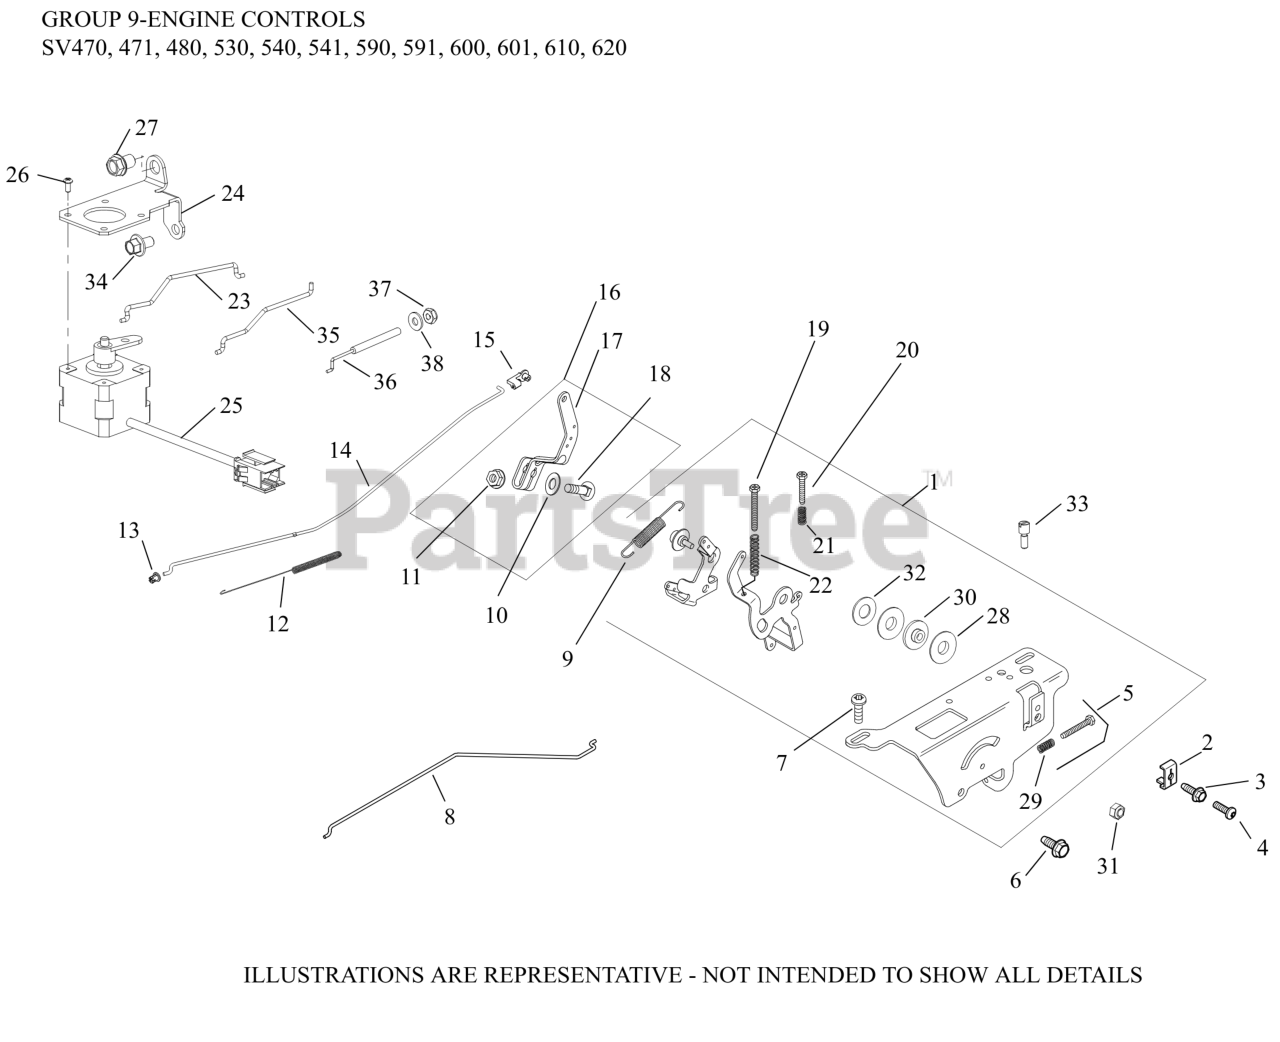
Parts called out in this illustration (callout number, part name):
1	SPEED CONTROL ASSEMBLY-USE 20 536 06-S
1	KIT, SPEED CONTROL ASSEMBLY
2	CLAMP, CABLE-(#2523753S)
5	KIT, IDLE ADJ SCREW & SPRING
7	SCREW, THREAD FORMING
8	LINKAGE, CHOKE
9	SPRING, GOVERNOR
10	WASHER, INT TOOTH LOCK 1/4"
11	NUT, FLANGE 1/4-20
12	SPRING, LINKAGE
13	BUSHING, LINKAGE RETAINING
14	LINKAGE, THROTTLE
15	BUSHING, THROTTLE LINKAGE
16	LEVER, GOVERNOR ASSEMBLY
17	LEVER, GOVERNOR - USE 20 090 11-S
18	BOLT, RD HD SQ NCK 1/4-20X1"
20	SCREW, PHL THD FRM M4X0.7X25
21	SPRING, SPEED CONTROL (SHORT)
28	WASHER, NYLON SHOULDER
29	SPRING, SPEED CONTROL
